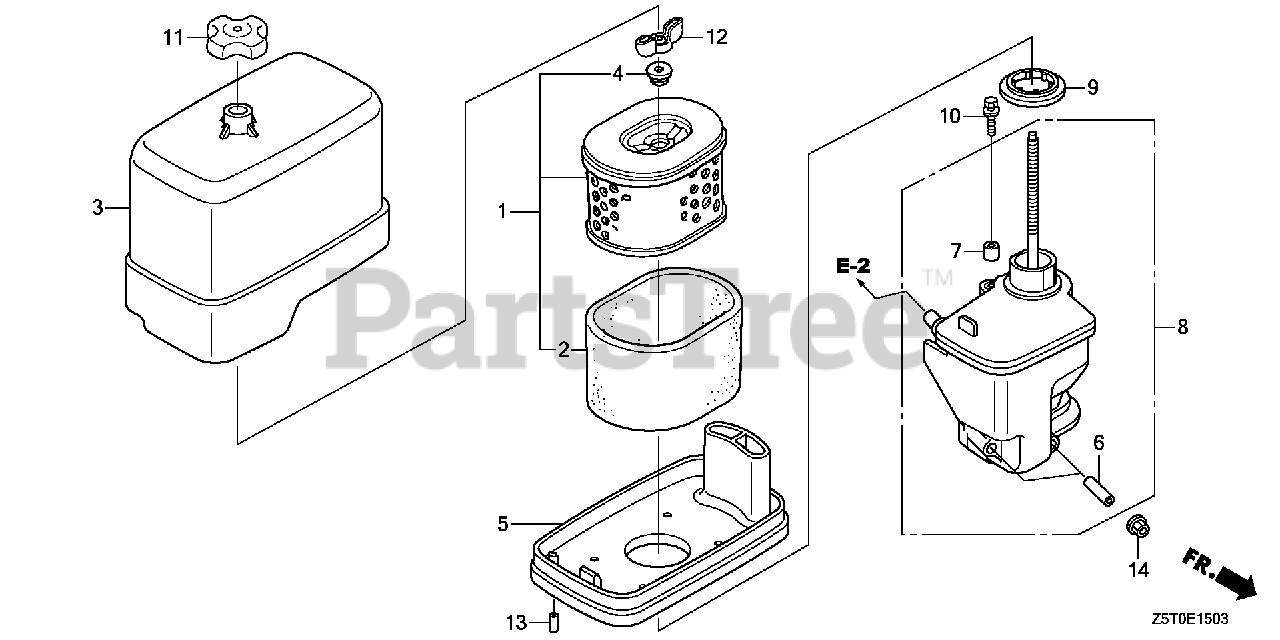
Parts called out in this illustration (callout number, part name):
1	ELEMENT, AIR CLEANER
2	FILTER (OUTER)
3	COVER, AIR CLEANER HOUSING
4	GROMMET, AIR CLEANER
5	NOSE, MUFFLER
6	COLLAR, AIR CLEANER
7	COLLAR B, AIR CLEANER
8	ELBOW, AIR CLEANER
9	GASKET, AIR CLEANER HOUSING
10	BOLT-WASHER (6X18)
11	NUT, AIR CLEANER COVER
12	NUT, TOOL BOX SETTING
14	NUT, FLANGE (6MM)
